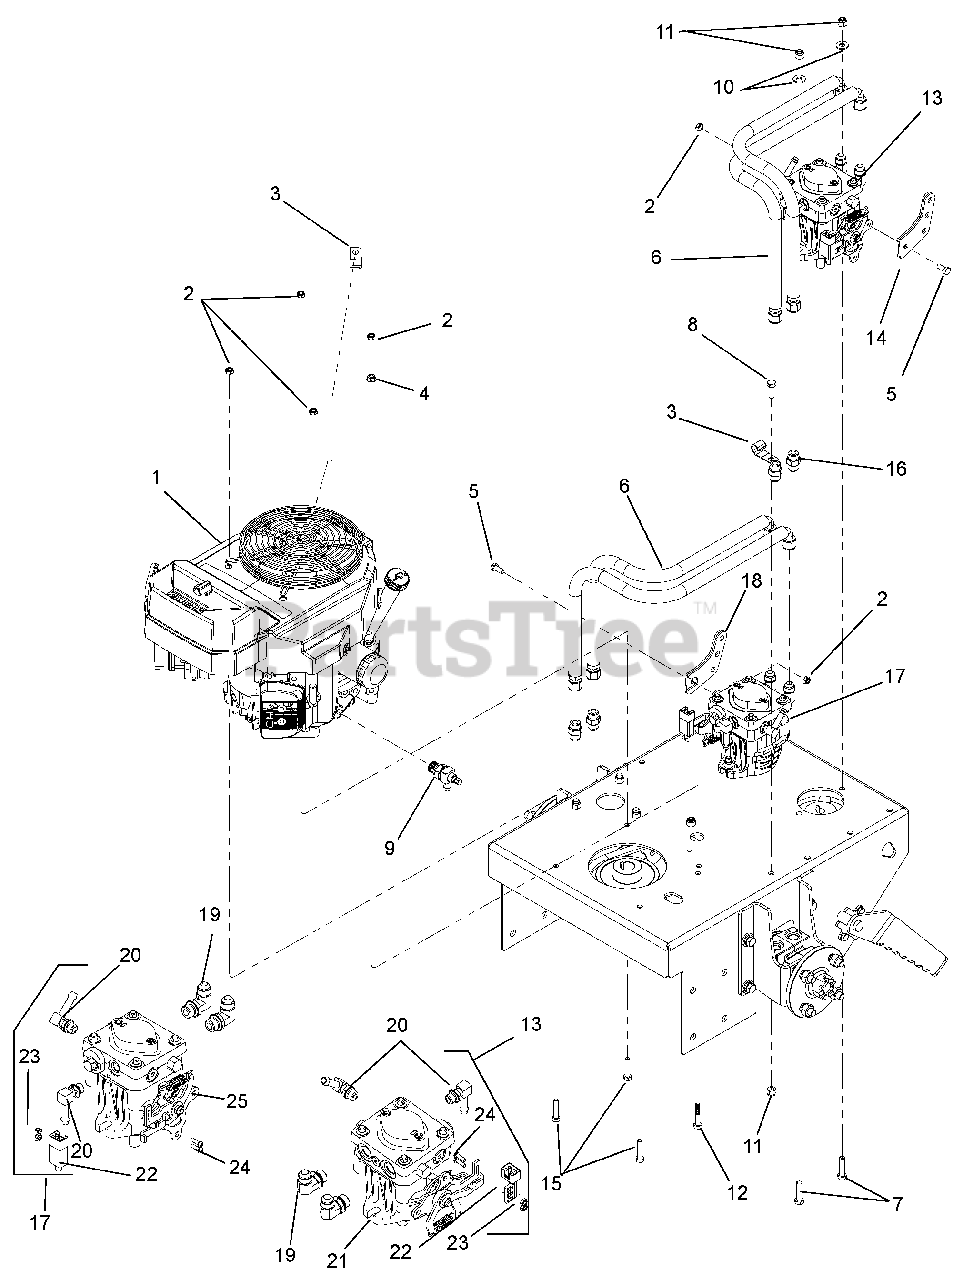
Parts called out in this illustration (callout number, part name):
1	ENGINE, KAWASAKI 15HP VERT
2	LOCKNUT, 5/16-18 NYLOC Y
3	P-CLIP, .500 INSULATED
4	LOCKNUT, 5/16-18 WHIZ Y
5	BOLT, 5/16-18 X .750 HEX 5 Y
6	HOSE, HYD 1/2 X 26 1/2 EZFLEX
7	BOLT, 3/8-16 X 1.50 HEX 5 Y
8	BOLT, 3/8-16 X 1.00 HEX 5 Y
9	OIL DRAIN FITTING
10	WASHER, .313 REG FLAT Y
11	LOCKNUT, 3/8-16 NYLOC Y
12	BOLT, 5/16-18 X 1.75 HEX 5 Y
13	ASSY, LH PUMP WALKBEHIND (INCLUDES ITEMS 19 – 24)
14	WLDT, CSWS LH HYDRO PUMP ARM
15	BOLT, 5/16-18 X 1.50 HEX 5 Y
16	FITTING, STRAIGHT
17	ASSY, RH PUMP WALKBEHIND (INCLUDES ITEMS 19, 20, 22 – 25)
18	WLDT, CSWS HYDRO PUMP ARM
19	FTG, ADP JIC-ORB 6801-08-08
20	FTG, 90 9/16 MOR X 3/8 HOSE
21	PUMP, HYD - PG-1HDA-D41X-XXXX RH
22	SWITCH, PLUNGER DP - N.O. - N.C.
23	LOCKNUT, 10-24 NYLOC Y
24	SCREW, 10-24X.625 PAN PHL MACY
25	PUMP, HYD - PG-1KDA-D61X-XXXX LH
